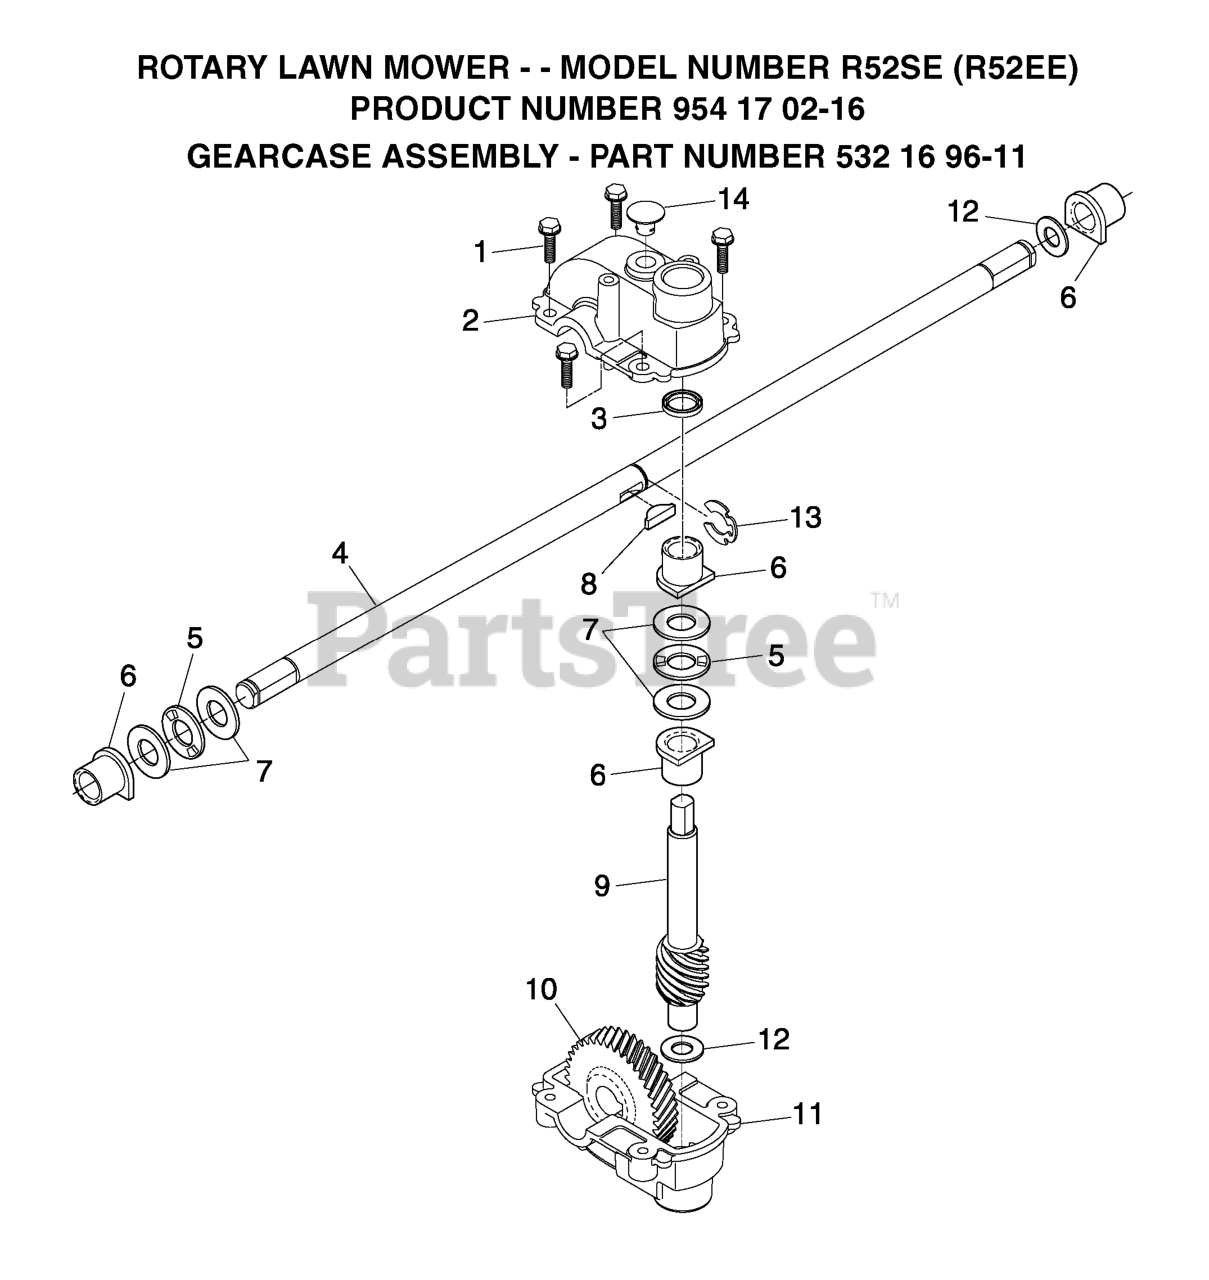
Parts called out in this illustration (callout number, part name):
1	Screw, Hex Washer Head #10-24 x .668
2	GEAR CASE, UPPER
4	TRANSMISSION ASM. (WALK)
5	BEARING, NEEDLE, THRUST
7	WASHER, THRUST
8	HI PRO KEY
9	SHAFT GEAR WORM
10	GEAR, HELICAL
11	GEAR CASE, LOWER
12	THRUST WASHER
14	PLUG.AUGER.GEAR.BOX.SNOW
